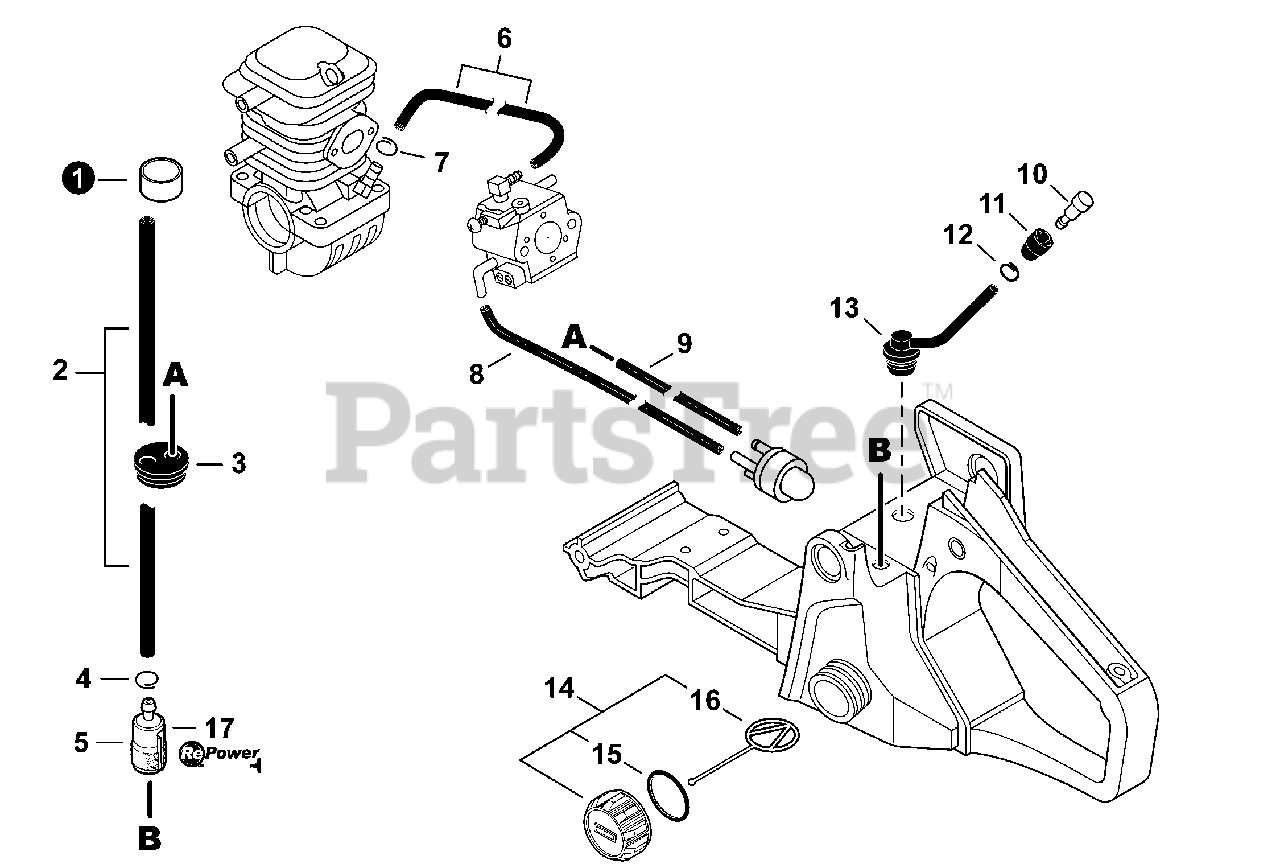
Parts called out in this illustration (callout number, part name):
1	TUBE 8×9×16
2	PIPE, FUEL 3×5×250
3	GROMMET, FUEL
4	CLIP Ø6
5	FILTER, FUEL
6	PIPE, PULSE 2.4×6×105
7	CLIP Ø6
8	PIPE 2.4×5×105 BLACK
9	PIPE, FUEL 2.4×5×200 BLACK
10	VENT ASSY
11	HOLDER, VENT
12	CLIP 6.5 MM
13	PIPE, VENT 3×6×65
14	CAP ASSY, FUEL
15	O-RING 22
16	CONNECTOR, CAP L= 60 MM
17	TUNE-UP KIT - REPOWER
